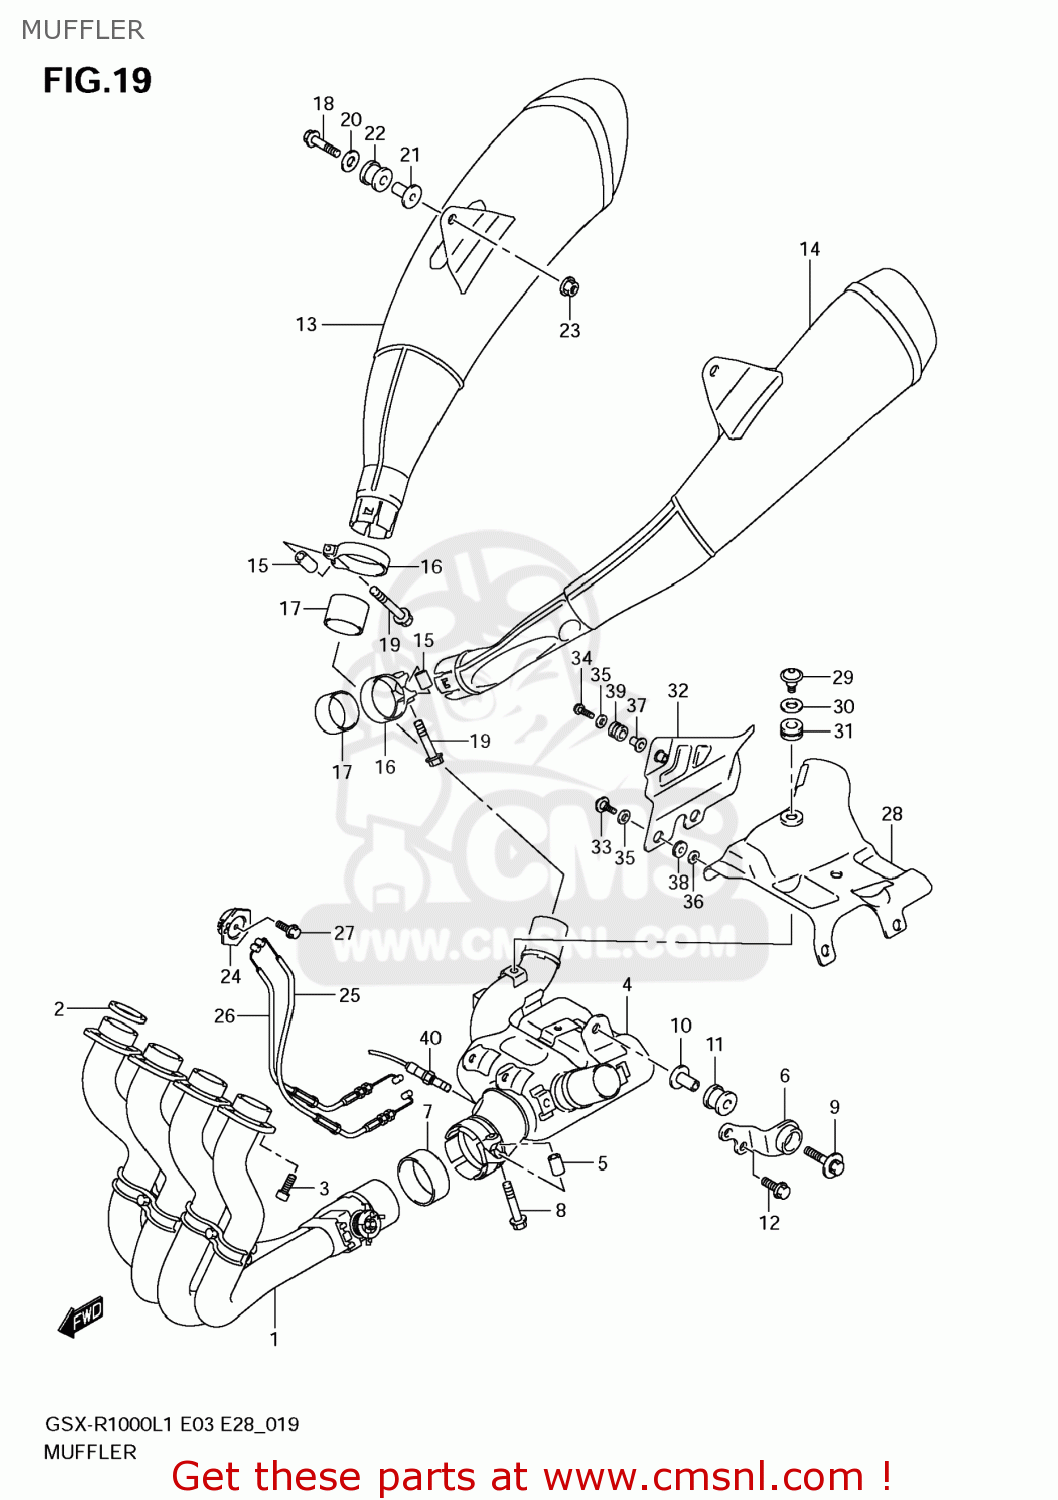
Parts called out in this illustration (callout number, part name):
1	PIPE,EXHAUST
2	GASKET,EXHAUST PIPE (NAS)
3	BOLT(8X25)
4	CHAMBER
5	SPACER,MUFFLER
6	BRACKET,CHAMBER SPRT
7	CONNECTOR,CHAMBER
8	BOLT(8X40)
9	BOLT(8X45)
10	SPACER(8.6X12X24.2)
11	CUSHION
12	BOLT
13	BODY,MUFFLER,R
14	BODY.MUFFLER.L
15	SPACER,MUFFLER
16	CLAMP,MUFFLER CONNECTOR
17	CONNECTOR,MUFFLER
18	BOLT(8X45)
19	BOLT(8X40)
20	WASHER(8.5X28X1.5)
21	SPACER(8.6X12X24.2)
22	CUSHION
23	NUT
24	PULLEY,CONTROLLER
25	CABLE,EXHAUST VALVE NO.1
26	CABLE,EXHAUST VALVE NO.2
27	BOLT
28	GUARD,CHAMBER HEAT NO.1
29	SCREW(6X12)
30	WASHER(8.5X18X1)
31	CUSHION
32	GUARD,CHAMBER HEAT NO.2
33	SCREW(6X20)
34	SCREW(6X25)
35	WASHER(6.5X15X1.0)
36	WASHER
37	SPACER(6.2X8.4X10.9)
38	CUSHION
39	CUSHION
40	SENSOR,OXYGEN
